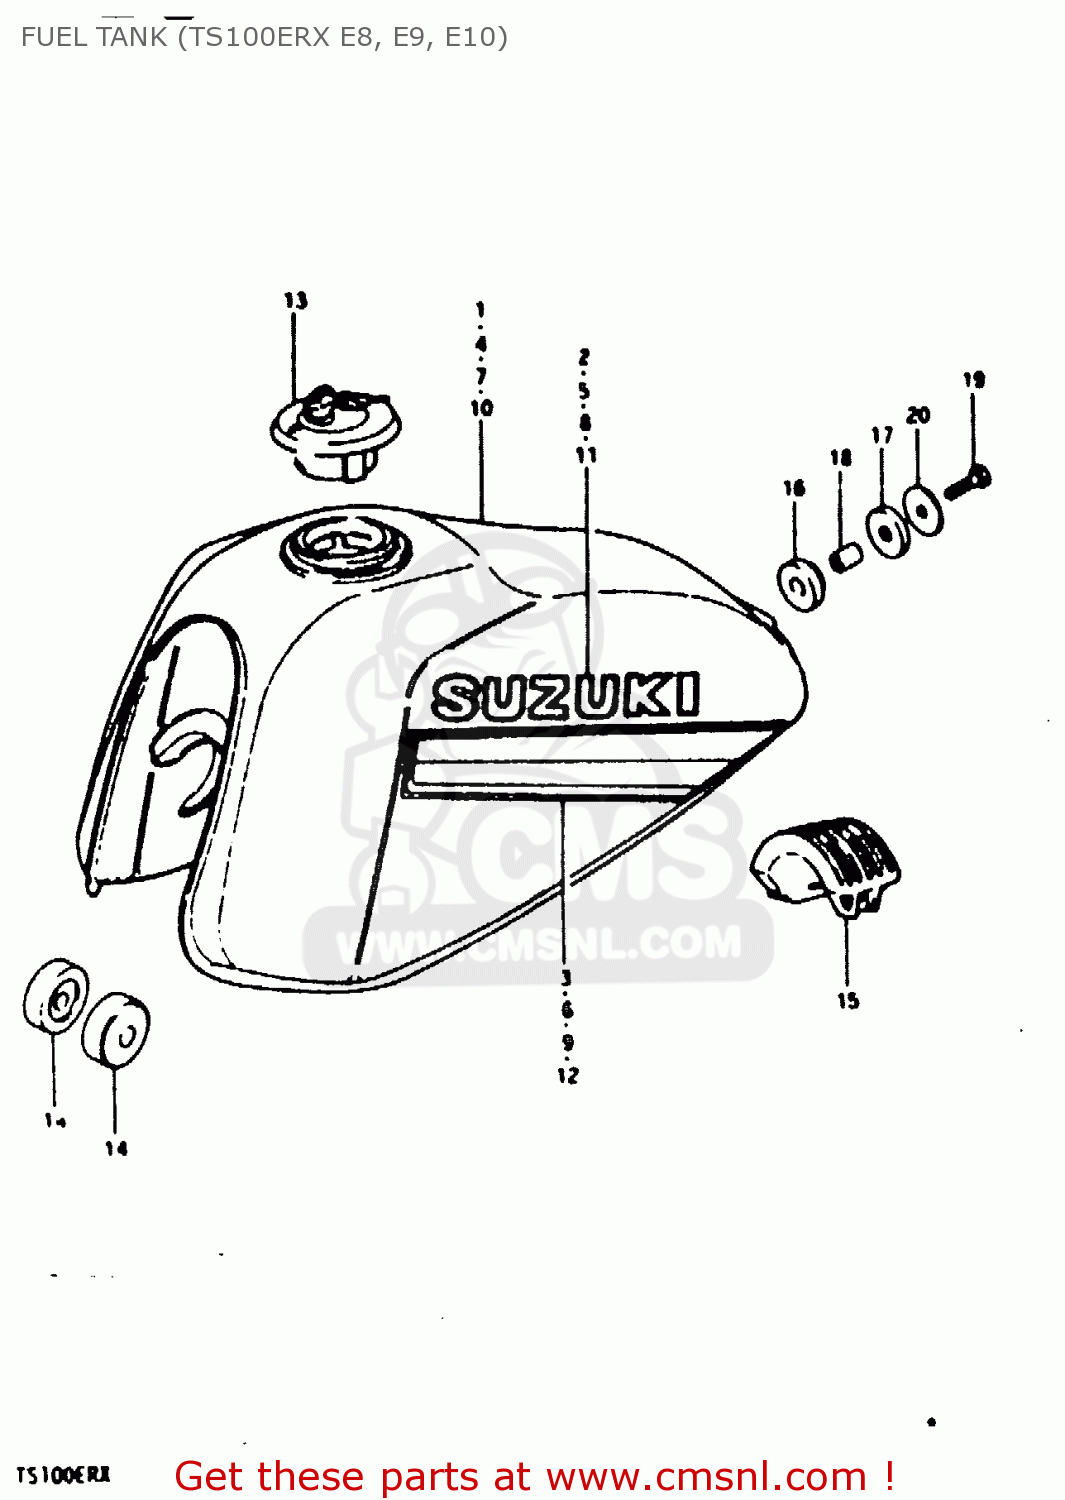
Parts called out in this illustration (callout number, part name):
1	TANK, FUEL (BLACK)
2	EMBLEM
3	TAPE SET
4	TANK, FUEL (YELLOW)
5	EMBLEM(BLACK)
6	TAPE SET
7	TANK, FUEL (RED)
8	EMBLEM
9	TAPE SET
10	TANK, FUEL (WHITE)
11	EMBLEM(BLACK)
12	TAPE SET
13	CAP SET,FUEL TANK
14	CUSHION
15	CUSHION,FUEL TANK
16	CUSHION
17	CUSHION
18	SPACER(8.5X12X19)
19	BOLT (8X30)
20	WASHER (8.5X29X1.6)
